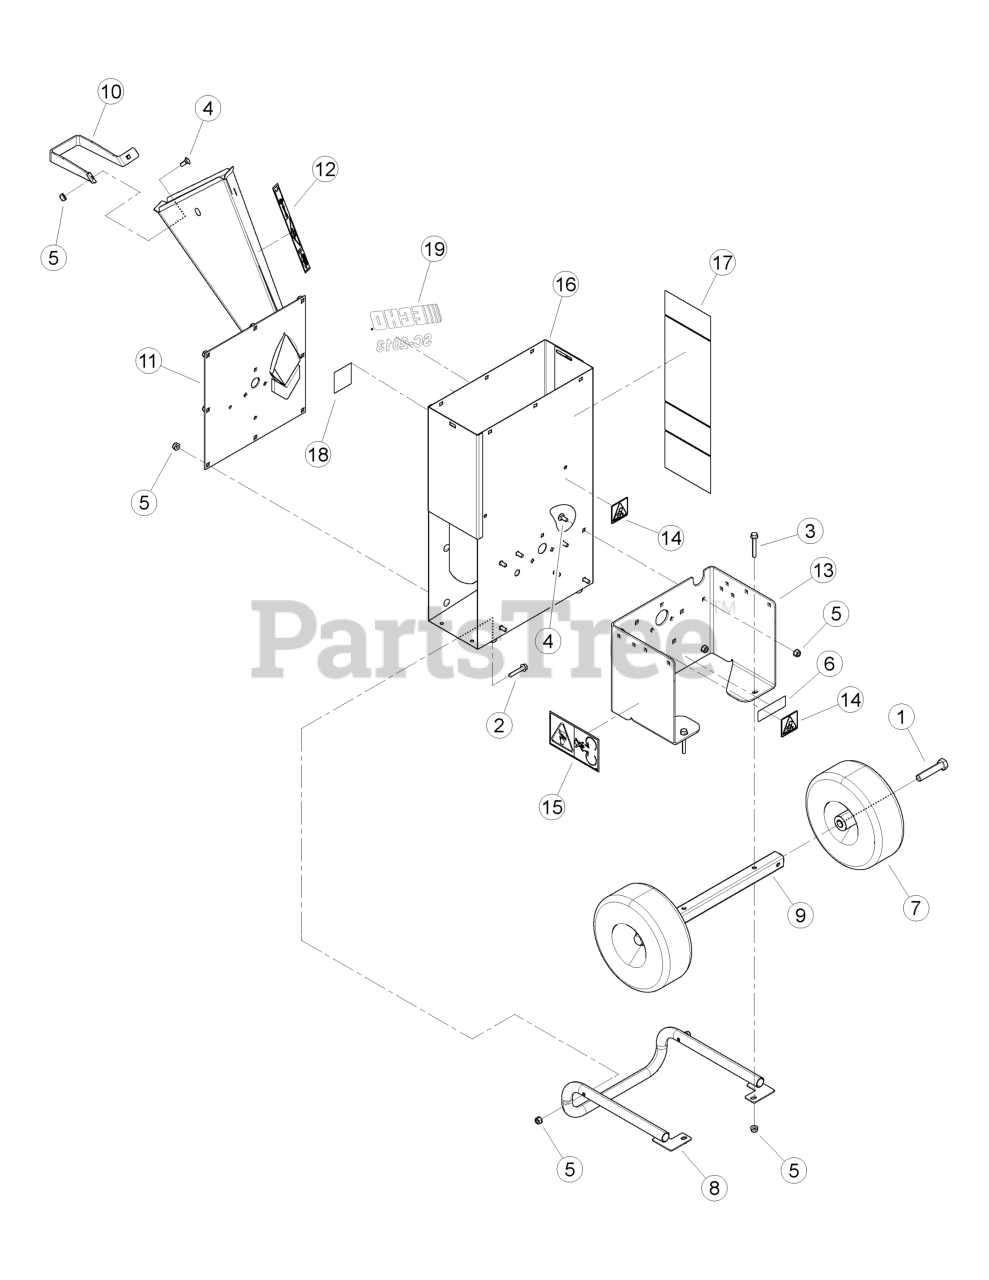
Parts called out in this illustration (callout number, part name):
1	BOLT, 5/8 × 3 HEX HD GR5 ZP
2	BOLT, 5/16 × 1-3/4 FLANGE NC
3	BOLT, 5/16 × 2-1/4 FLANGE NC
4	BOLT, 5/16 × 3/4 GR5 CRG NC ZP
5	NUT, 5/16-18 NYLOCK FLANGE
6	DECAL, SERIAL NUMBER
7	ASSEMBLY, 410/350-4 FLAT-FREE WHEEL
8	WELDMENT, SUPPORT LEG SHORT
9	WELDMENT, AXLE 3 IN CHIPPER
10	HANDLE, CHIPPER CHUTE 3 IN
11	ASSEMBLY, 3 IN FRONT PLATE
12	DECAL, 3" CHIPPER CHUTE
13	ASSEMBLY, BASE 3 IN CHIPPER SERVICE
14	DECAL, SHIELD DANGER ISO
15	DECAL, BLADE DANGER ISO
16	ASSEMBLY, 3 IN DOM BODY COMPONENTS
17	DECAL, 3" CHIPPER BODY SIDE
18	DECAL, SPARK ARRESTOR
19	DECAL, MODEL ECHO SC-2013
